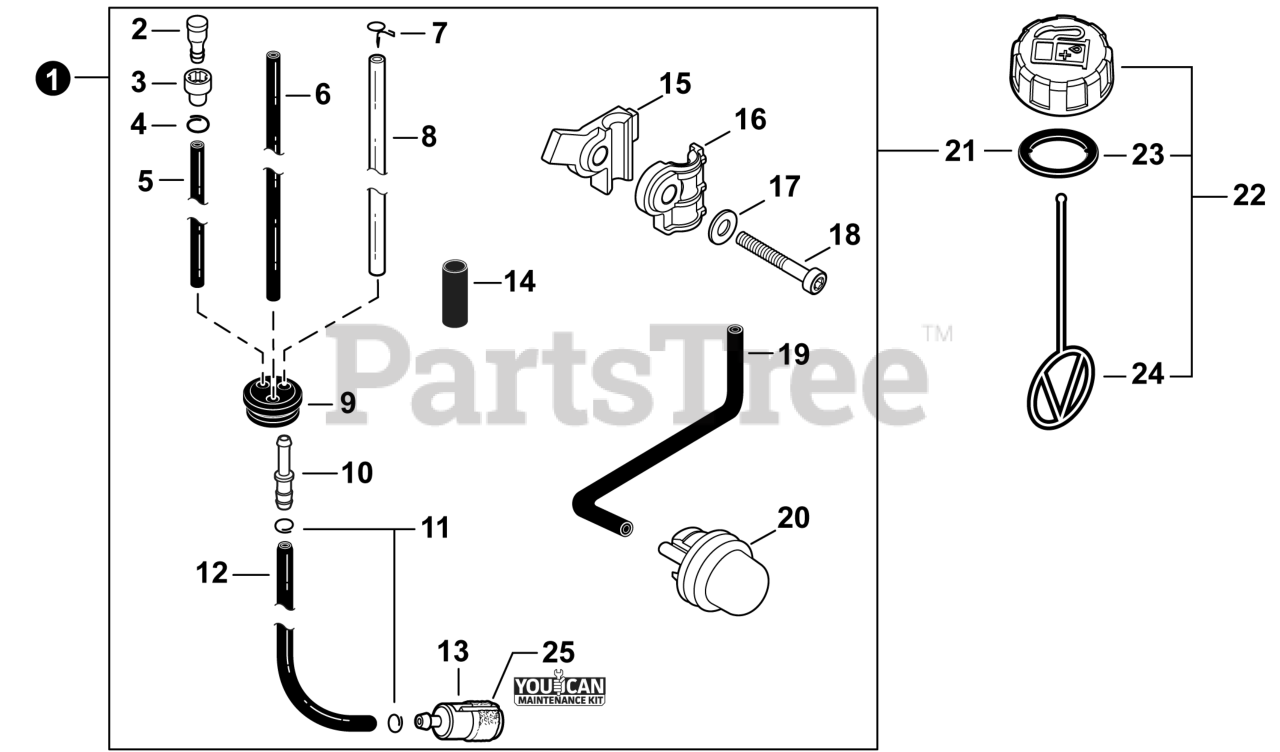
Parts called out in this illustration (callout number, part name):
1	FUEL SYSTEM KIT - YOUCANT
2	VENT ASSY
3	HOLDER, VENT
4	CLIP Ø6.5 MM
5	PIPE, FUEL 3×6×130 BLACK
6	PIPE, FUEL 2.4×5×200 BLACK
7	CLIP, SPRING Ø5.2
8	PIPE, FUEL, 3.5X6X210 2020
9	GROMMET, FUEL
10	CONNECTOR, PIPE Ø5ר3.5
11	CLIP Ø6
12	PIPE, FUEL 3×5×105L BLACK
13	FILTER, FUEL
14	TUBE, FUEL LINE 16×18×L40
15	CLAMP, LOWER
16	CLAMP, UPPER
17	WASHER, FLAT 5.5×10×0.8
18	BOLT, TORX 5×25
19	PIPE, PURGE 2.5×5×140
20	BULB, PURGE
21	GASKET, FUEL CAP
22	CAP ASSY, FUEL
23	GASKET, FUEL CAP
24	CONNECTOR, CAP L= 100 MM
25	TUNE-UP KIT - YOUCANT
